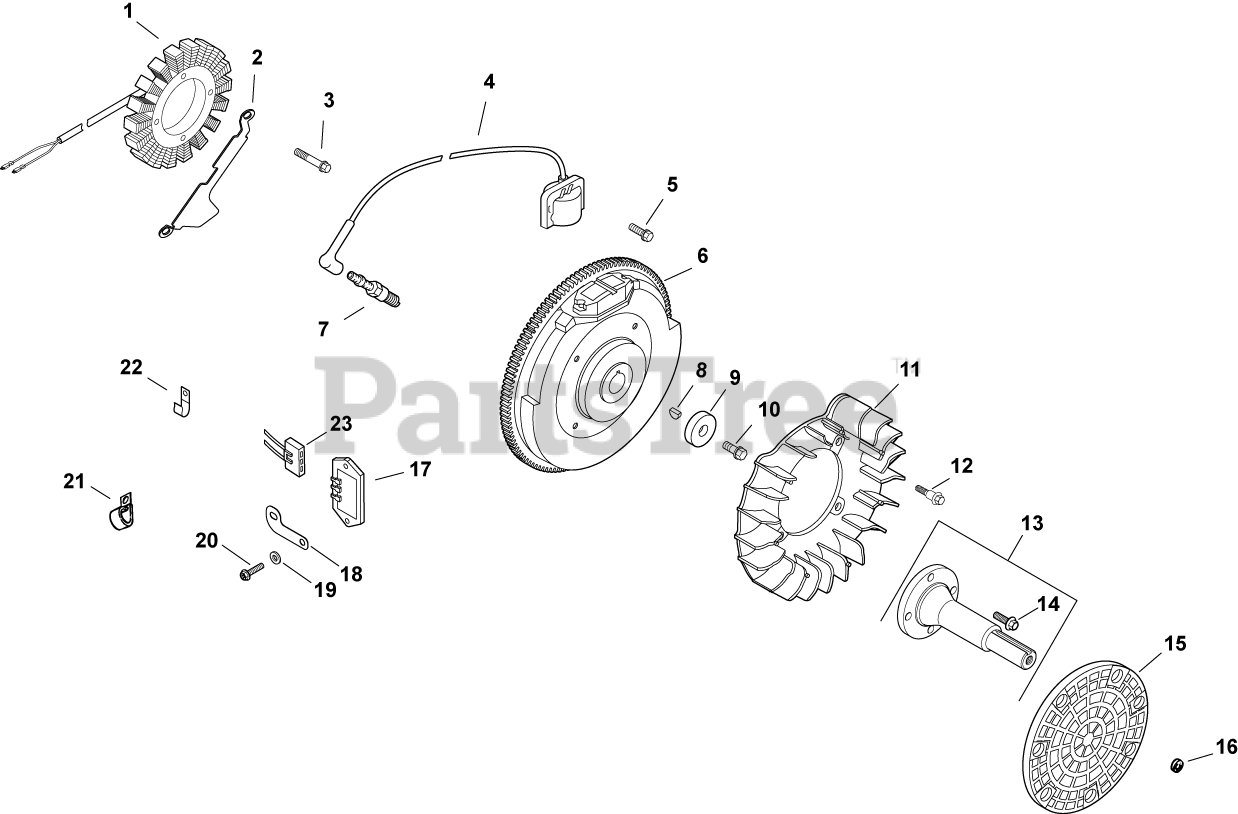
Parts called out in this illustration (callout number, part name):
1	KIT, 15 / 20 AMP STATOR
2	BRACKET, STATOR WIRE-USE 24 126 139-S
3	SCREW, M5X0.8X25 - (#25086402S)
4	MODULE, IGNITION-USE 24 584 45-S
5	SCREW, FLG THD FRM M5X.8X20-(#25086399S)
7	PLUG, SPARK (STD)
8	KEY, 3/16" X 5/8"
9	WASHER, FLAT 13/32"
10	SCREW, FLG M10X1.5X45 - (#25086361S)
11	FAN (KM)-USE 24 157 15-S
12	BOLT, SHOULDER
13	SHAFT, FRONT DRIVE
14	SCREW, FLG M8X1.25X25
15	SCREEN, GRASS-USE 24 755 171-S
17	REG/RECTIFIER (20/25 AMP)-USE 25 403 20-
18	BRACKET, GROUND STRAP USE 24 518 12-S
19	WASHER, FLAT 3/16"
20	SCREW, PHL HD #11-16X7/8"
22	CLIP, CABLE
23	CONNECTOR
